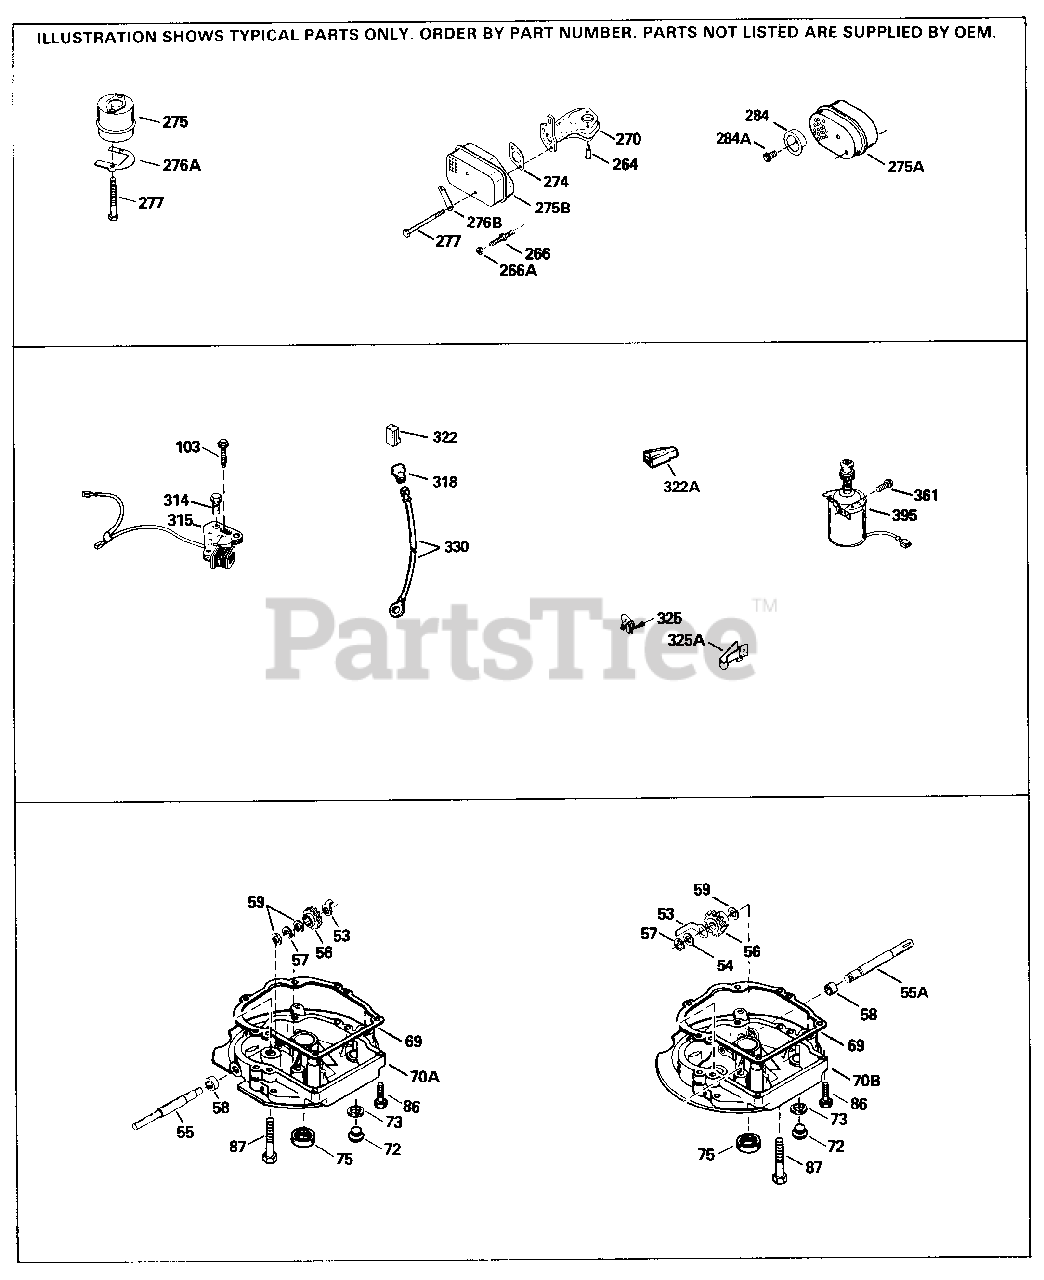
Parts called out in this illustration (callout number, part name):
69	* Gasket, Mounting flange
72	Plug, Oil drain (Incl. 73)
73	* Drain Plug Gasket Do not use w/plast ic plug
75	Oil Seal
86	Screw, 1/4-20 x 1-1/4"
103	Screw, Torx T-15, 10-24 x 1"
264	Screw, Torx T30, 1/4-20 x 1-7/32"
266	Stud, Manifold
266A	Nut & Lock Washer 1/4-28
270	Manifold Assy., Exhaust
275A	Muffler
277	Screw, 5/16-18 x 2-1/2"
325	Wire Clip
